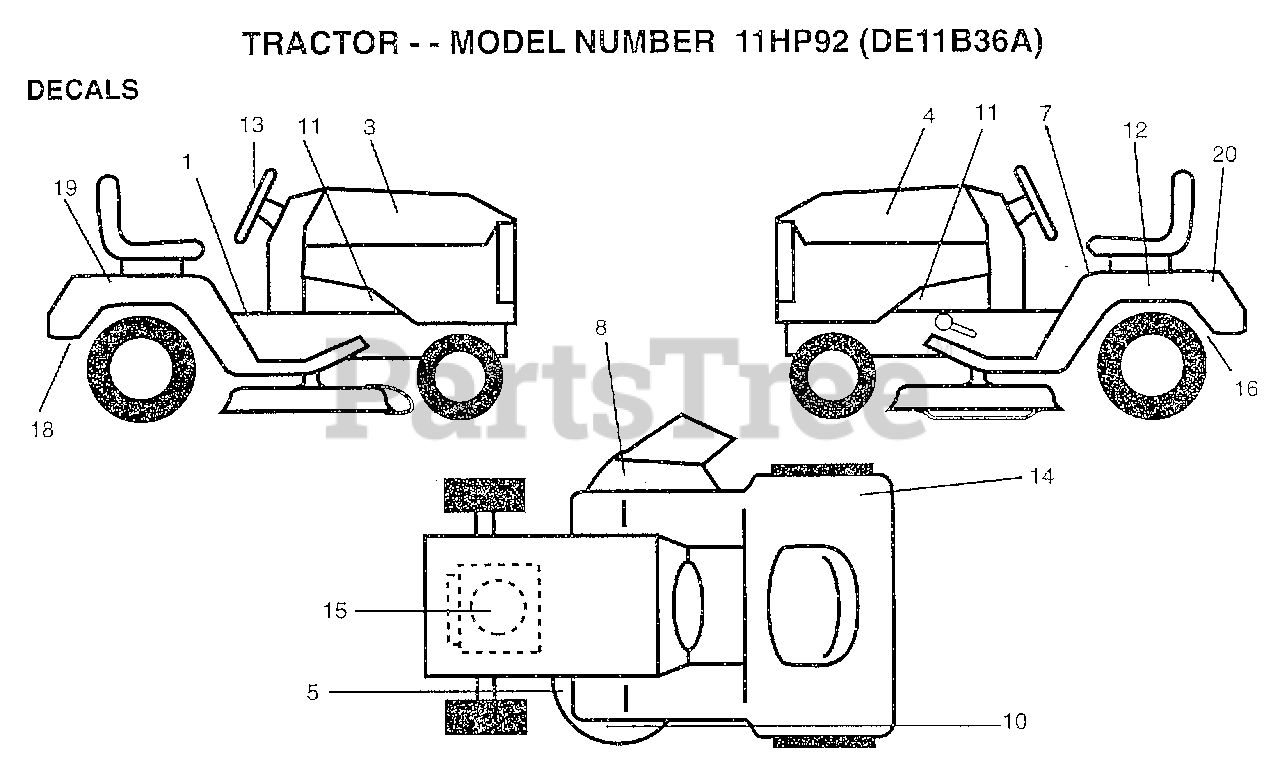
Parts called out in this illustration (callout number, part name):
1	DECAL CLUTCH/BRAK
3	DECAL.HOOD.RH
4	DECAL.HOOD.LH
5	DECAL.V.BELT
7	DECAL.READ.O.MANU
8	DECAL.DANGER.CUTF
10	DECAL.DECK.MOWER
11	"DECAL CHASSIS,HOT"
12	DECAL.BATRY.3-3908
13	DECAL.INST.STEERING
16	DECAL.DRAWBAR.LDL
18	DECAL.EURO.ST.CE.
19	DECAL.FENDER.RH
20	DECAL FENDER LH
